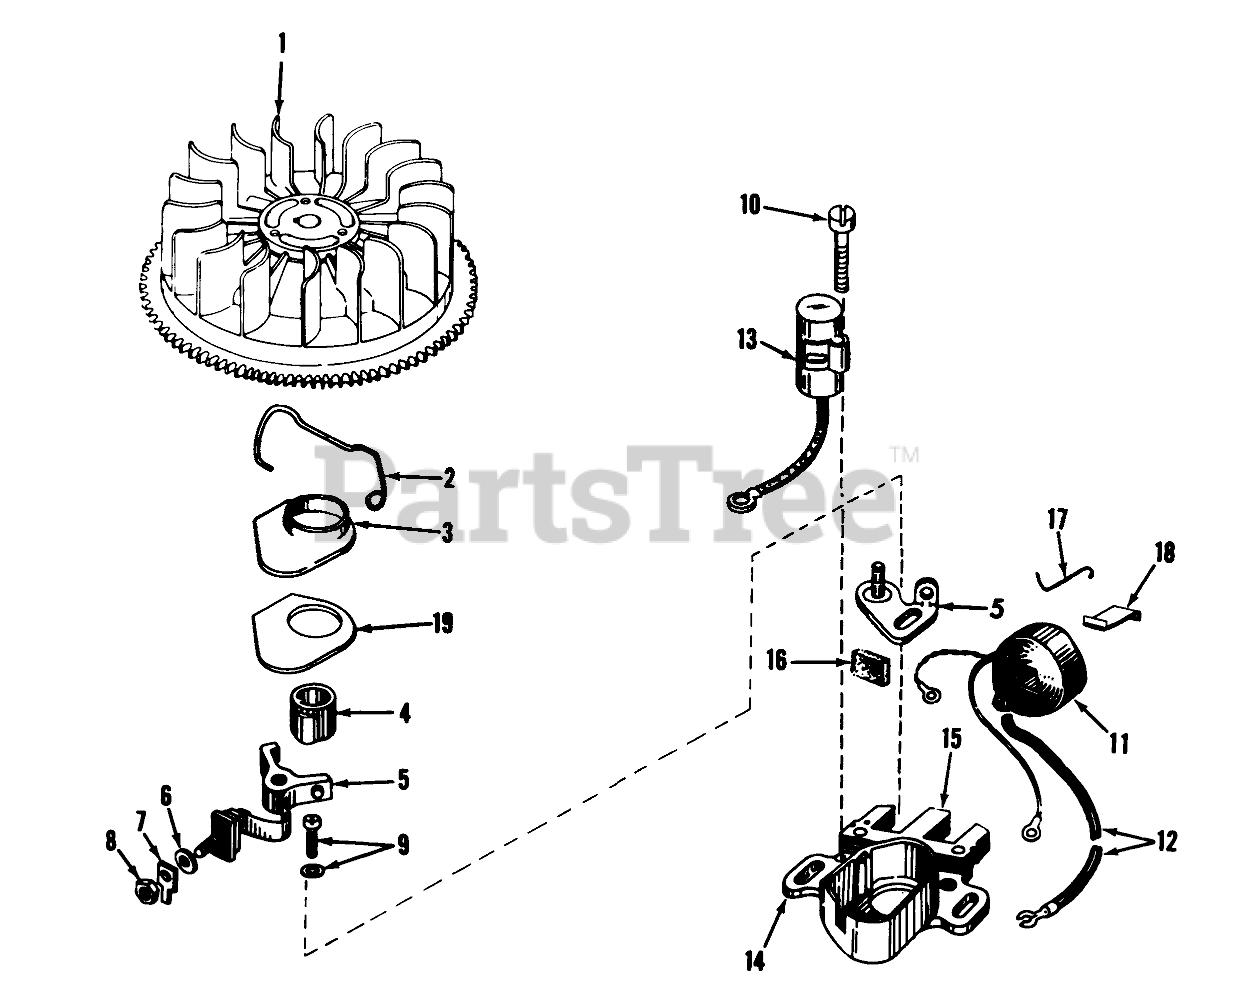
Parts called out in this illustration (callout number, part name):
1	Flywheel
2	Spring Breaker Box
3	Cover, Dust
4	Cam-Breaker
5	Breaker Assy.
7	Terminal
9	Breaker Screw
10	Condenser Screw
11	Coil Assy., (Incl. #12)
12	Wire, Lead
13	Condenser
14	Core & Plate
15	Stator Assembly, (Incl. #2, 3, 5 thru 14 & 16 thru 19)
16	Felt,Cam Wiper
17	Clip, Coil
18	Spring Coil Wedge
19	Gasket, Dust Cover
